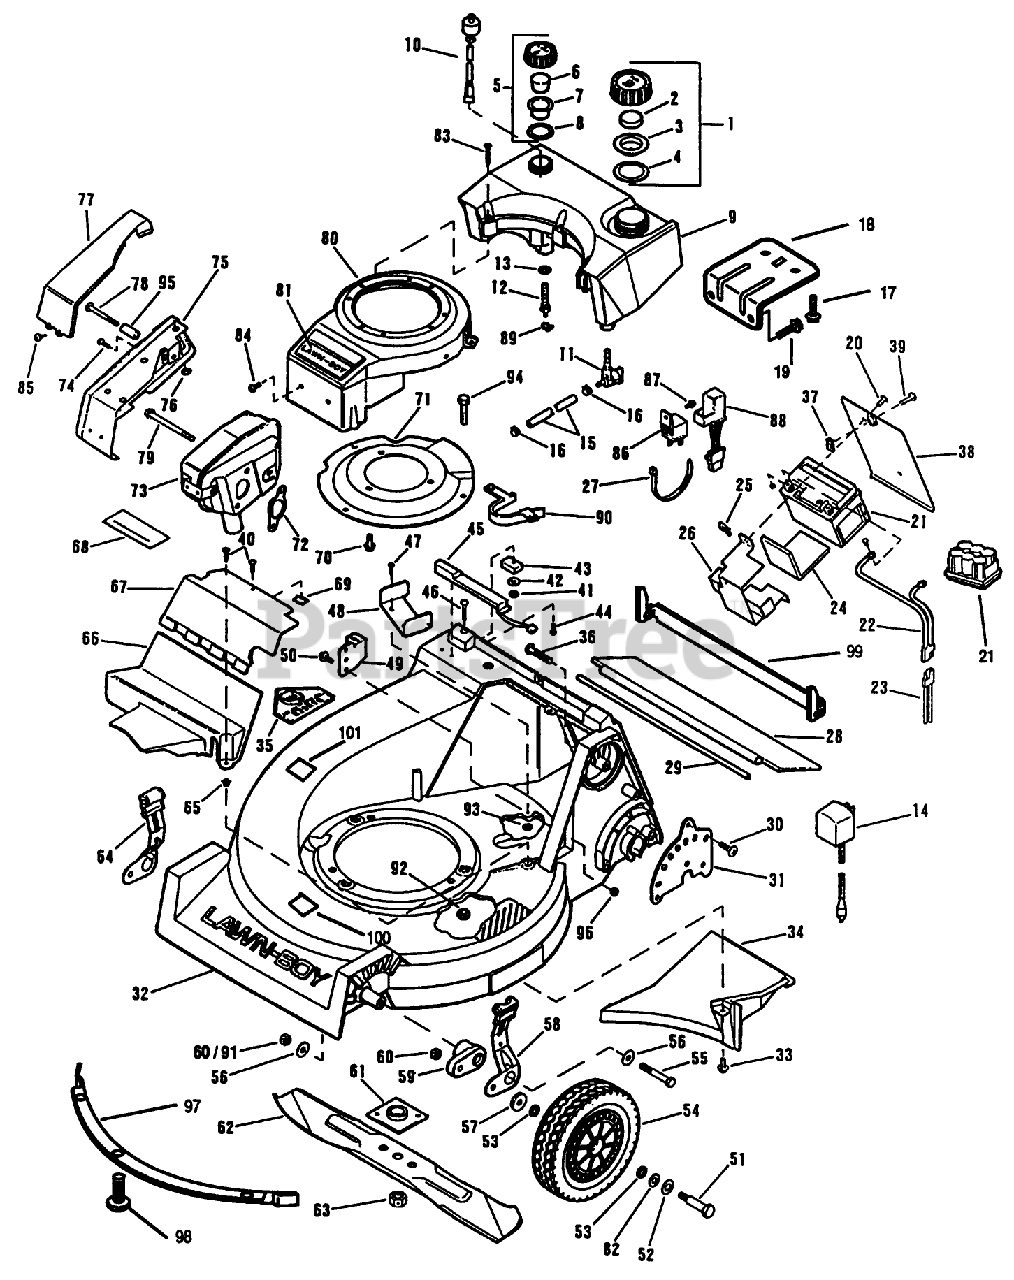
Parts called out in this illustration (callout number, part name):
1	CAP AY - FUEL M
2	BAFFLE - FOAM SM
4	GASKET-FUELCAP SM
5	CAP AY. OIL M
6	FILTER S
10	SWITCH AY-OIL S
11	DISC/LB SER.BUL.#6
13	O-RING SM
15	GAS LINE SM
16	HOSE CLAMP SM
17	DISC/LB SER.BUL.#6
18	DISC.LB SER BUL.#6
19	SCREW-HEX W.H. SM
23	WIRE HARNESS
24	PAD-BATTERY
25	SPEED NUT ARDEN
27	TIE-CABLE
30	SCREW-BHTF
31	PLATE HGT CMS
34	CHUTE BAFFLE NYL
37	SPEED NUT LARSON
38	DOOR-ACCESS ELECT.
39	SCREW-CROSS RECESS
48	Belt Guide
51	BOLT WHEEL QUAL
52	SPACER
53	WASHER
54	WHEEL&TIRE 8" TRI
56	WASHER-PLAIN
57	WASHER
58	KNOB & SPRING CMS
59	ARM HGT ADJ *BLACK
60	NUT-JAM, LOCKING
61	PLATE AND COLLAR ASM
63	NUT-BLADE
64	KNOB & SPRING CMS
65	NUT-CLIP
69	NUT-SPEED
71	PLATE SM
72	GASKET - EXH SM
74	SCREW S
75	MUFFLER GUARD&COVR
76	NUT-PUSH
77	COVER MUFFLER CP
78	SCREW SM
79	SCREW-SEMS
81	APPLIQUE SM
82	WASHER
83	DISC.LB SER.BUL.#6
85	SCREW SM
91	LOCKNUT
92	NUT-LOCK F
93	NUT C/LOCK E
94	SCREW-HH
95	SPACER S
96	LOCKNUT E
